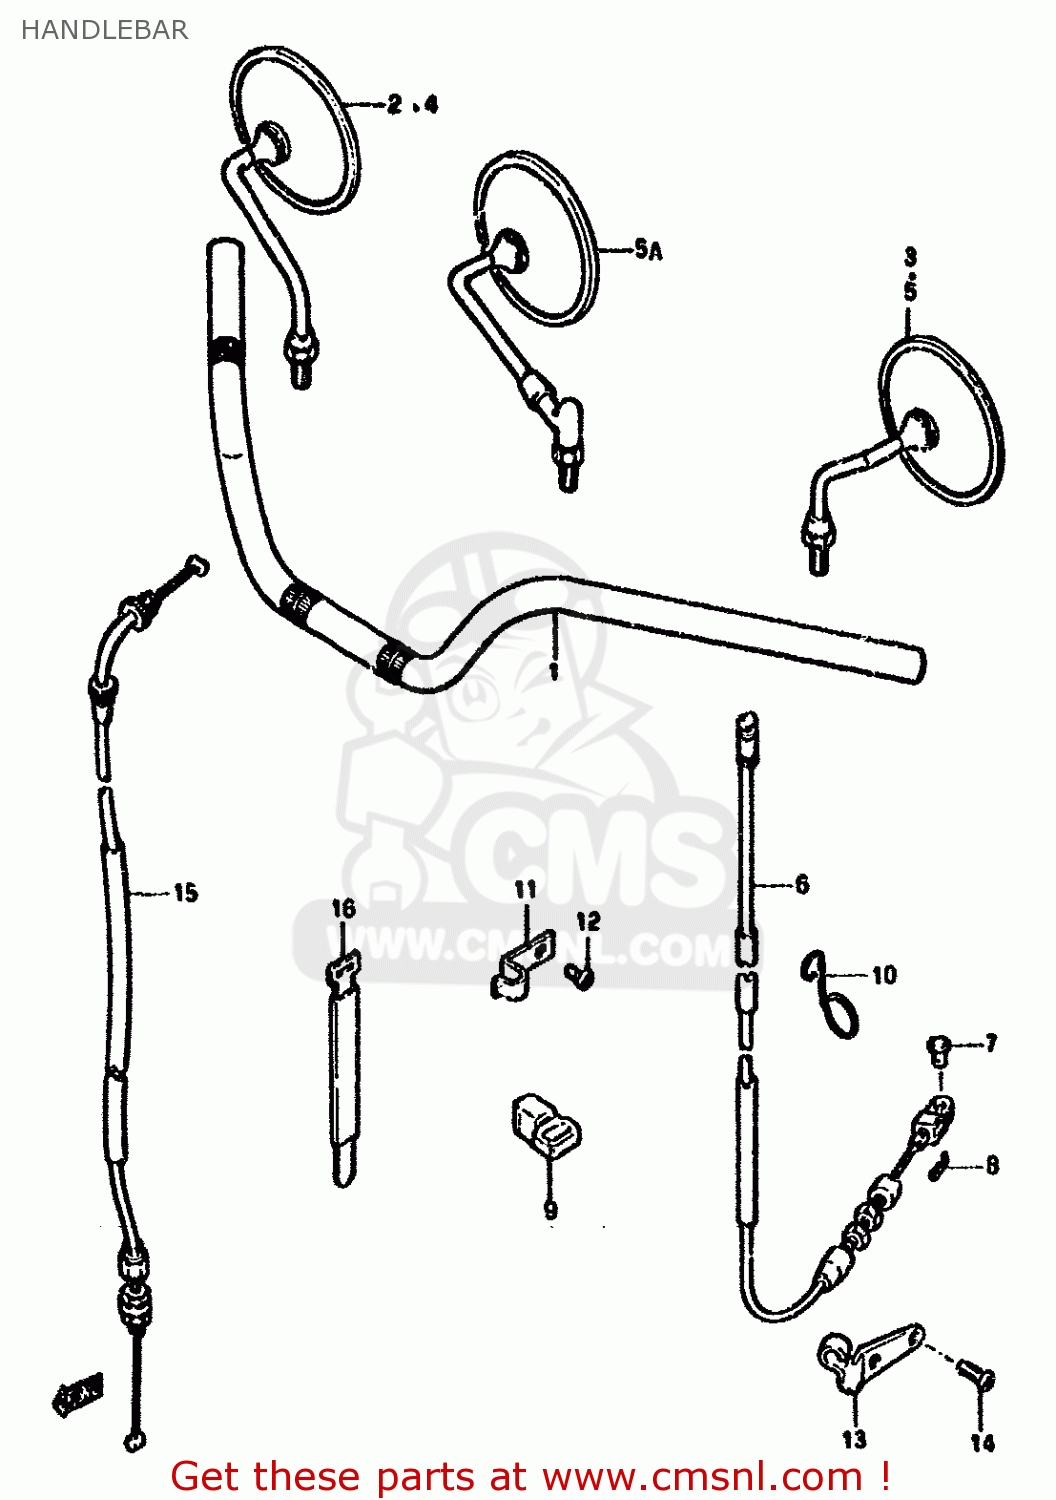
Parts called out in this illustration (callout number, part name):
1	HANDLEBAR
2	MIRROR ASSY,RH
3	MIRROR ASSY,LH
4	MIRROR, REAR VIEW RH
5	MIRROR, REAR VIEW LH
5A	MIRROR ASSY,RH
6	CABLE ASSEMBLY,CLUTCH
7	PIN(L:13)
8	PIN
9	GUIDE,CLUTCH CABLE
10	GUIDE,CABLE
11	CLAMP,CLUTCH CABLE NO.1
12	SCREW
13	STOPPER,CLUTCH CABLE
14	SCREW
15	CABLE ASSY,THROTTLE
16	CLAMP(L:250)
